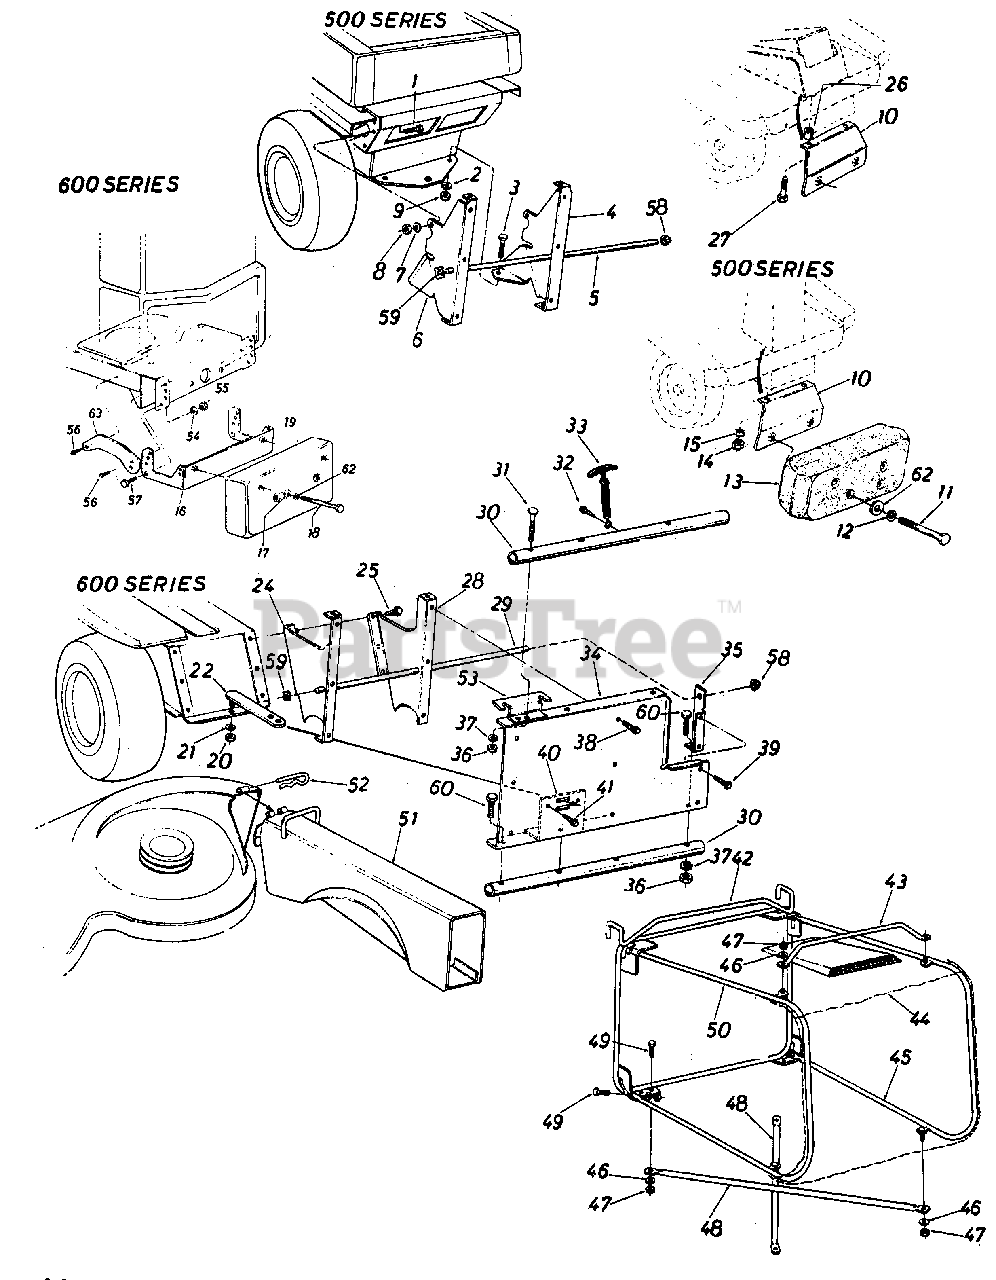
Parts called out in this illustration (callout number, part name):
1	Hex Bolt 5/16-18 x 1.00" Lg. *
2	L.-Wash. 5/16" I.D.*
3	Hex Bolt 5/16-18 x 1.00" Lg. *
4	CatcherSupport Brkt-R.H.
7	L.-Wash. 5/16" I.D.*
8	Hex Nut 5/16-18 Thd.*
9	Hex Nut 5/16-18Thd.*
10	Counterweight Bracket
11	Hex Bolt 3/8-16 x 4.5" Lg.*
12	Belleville Wash. .400" I.D. x.88" O.D.
13	Front Counterweight 381bs
14	Hex Nut 5/16-18Thd.*
15	L.-Wash. 5/16" I.D.*
16	Counterweight Bracket
17	Belleville Wash. .400" I.D. x.88" O.D.
18	Hex Bolt 3/8-16 x 4.5" Lg. *
19	Front Counterweight 38 Ibs.
20	Hex Jam Nut 1/2-13 0 Thd. *
21	L.-Wash. 1/2" I.D.*
25	Hex Wash. Hd. Self Tap Scr. 5/16-18 x .75 Lg.*
26	Spacer.380" I.D. x 1.00" O.D. x.320" Lg.
27	Not Part of Kit
28	Catcher Support Brk t. R . H .
31	Curved Carriage Bolt 5/16-18 x 1.75" Lg.
32	Hex "AB"-TapScr. 1/4" x .62" Lg.
33	Hood Latch Ass'y.
34	Grass Catcher Adapter
35	Grass Catcher Support Brk't.-R.H.
36	HexNut5/16-18Thd.*
37	L.-Wash. 5/16" I.D.*
38	Hex Wash. Hd. Self Tap Scr. 1/4-20 x . 50" Lg.
39	Hex Wash. Hd. Self Tap Scr. 1/4-20 x . 50" Lg.
40	Hitch Bracket
41	Hex Wash. Hd. Self Tap Scr. 1/4 20 x .50" Lg.
42	Grass Bag Frame Ass'y.
43	Grass Catcher Handle 26.75
44	G rass Catcher Bag
47	Hex L.-Nut 1/4-20 Thd.
48	Bottom Cross Brace 30.36" Lg. *
49	Hex Bolt 1/4-20 x .62" Lg. *
52	Not Part of Kit
53	Grass Catcher Support Plate
54	L.-Wash. 7/16" I.D.*
55	Hex Nut 7/16-20 Thd.*
56	Hex AB Tap Scr. 5/16-18 x 1" Lg.
57	HexBolt 7/16-20 x 1.00" Lg. *
59	Speed Nut
60	Hex Bolt 5/16-18 x 1.75" Lg. *
62	Fl.-Wash. .390" I.D. x 1.12" O.D. x .187 Thk.
